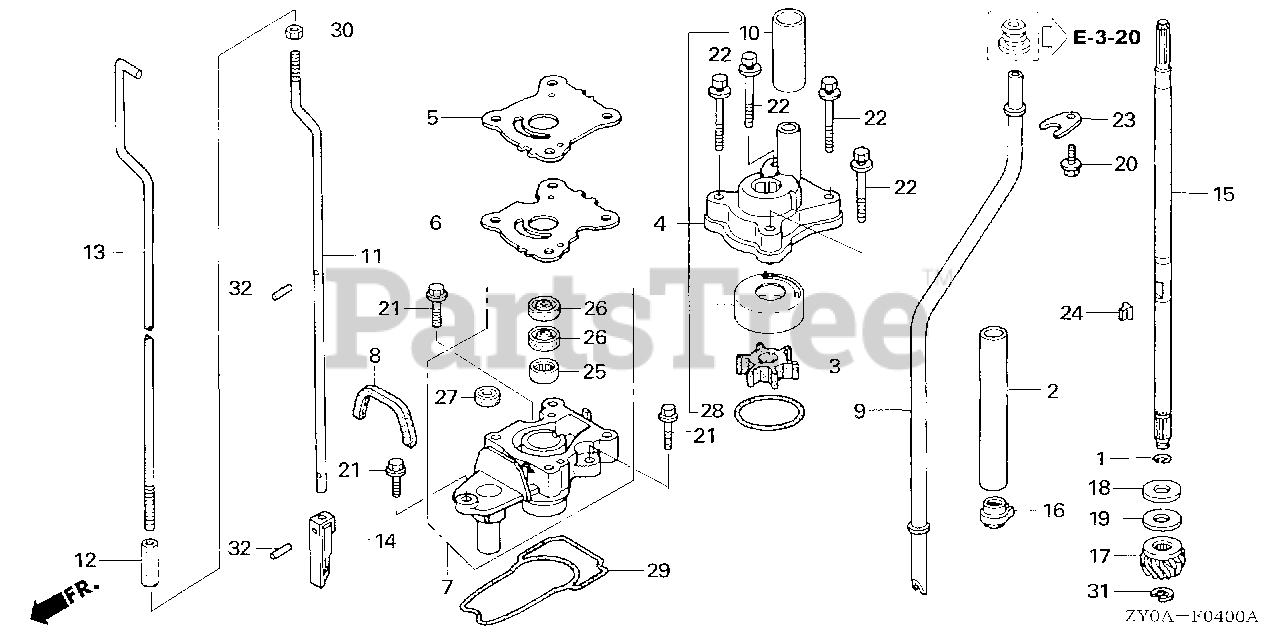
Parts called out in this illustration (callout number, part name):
1	CLIP, VALVE GUIDE
2	GUIDE, OIL (S,L)
3	IMPELLER, PUMP (UL)
4	HOUSING ASSY., IMPELLER
5	COVER, IMPELLER
6	GASKET, IMPELLER
7	HOUSING, WATER PUMP (S,L)
8	GROMMET, WATER PUMP HOUSING
9	TUBE, WATER (S)
10	RING, WATER TUBE SEAL
11	ROD B, SHIFT (S)
12	JOINT, SHIFT ROD
13	ROD A, SHIFT (S)
14	ROD, PUSH
15	SHAFT, VERTICAL (S)
16	SLINGER, OIL (UL)
17	GEAR, PINION
18	WASHER A, THRUST BEARING
19	WASHER B, THRUST BEARING
19	WASHER C, THRUST BEARING
20	BOLT, FLANGE (6X12)
21	BOLT, FLANGE (6X20)
22	BOLT-WASHER (6X50)
23	PLATE, WATER TUBE SETTING
24	KEY, WOODRUFF
25	BEARING, NEEDLE (15X21X12)
26	SEAL, WATER (15X24X5)
27	SEAL, WATER (6MM)
28	O-RING (42.2X2.4)
29	O-RING, WATER PUMP HOUSING
30	NUT, HEX. (6MM)
31	E-RING (8MM)
32	ROLLER (2.5X11.8)
